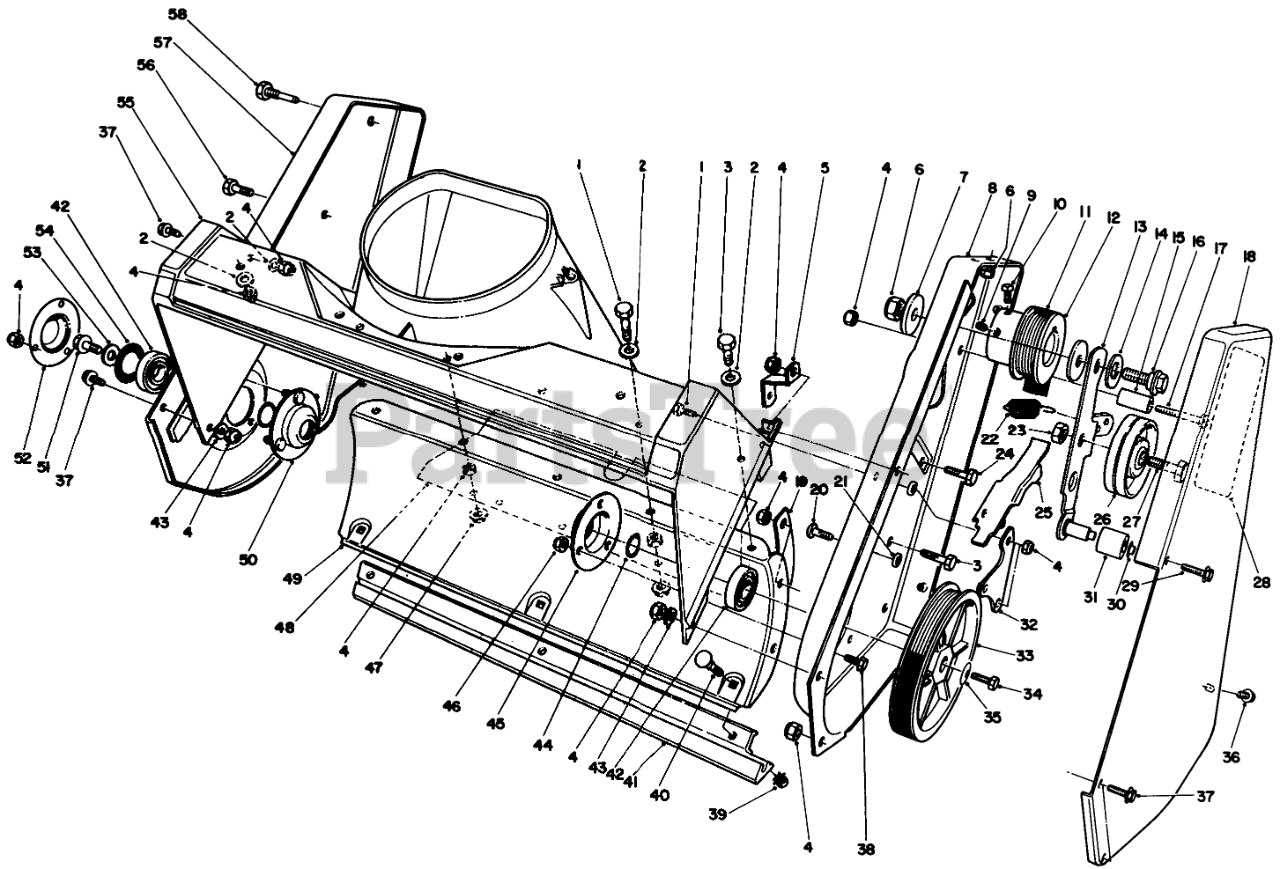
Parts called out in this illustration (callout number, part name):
1	SCREW-HH
2	WASHER-FLAT
3	SCREW-HH
4	NUT-LOCK, NI
5	BRACKET-HOUSING
6	NUT-LOCK, NI
7	WASHER-PIVOT
8	Sideplate-L.H.
9	SCREW-HSH
10	SCREW-SQH
11	BELT - DRIVE
12	ENGINE PULLEY
13	Idler Arm Assembly (Incl. Ref. #29 & 30)
14	WASHER
15	SLEEVE-GUIDE, BELT
16	SCREW-SHOULDER
17	SCREW-HH
18	Cover-Drive
19	BRACKET-HOUSING, LOWER
20	SCREW-HSBH
21	SPACER-PLATE, PIVOT
22	SPRING-EXTENSION
23	NUT-LOCK, CONE
24	SCREW-HH
25	BRAKE-ARM
26	PULLEY-IDLER
27	SCREW-HH
28	DECAL
29	SCREW-HWH, TAP
30	NUT-PUSH
31	ROLLER-BRAKE
32	PIVOT PLATE ASM
33	ROTOR PULLEY ASY
34	SCREW-HH
35	WASHER-BELLEVILLE
36	SCREW
37	SCREW-HWH
38	SCREW-SHH
39	NUT-KEPS
40	SCREW-CARR
41	SCRAPER
42	BEARING-BALL
43	WASHER-FLAT
44	WASHER-THRUST
45	FLANGE-BEARING
46	NUT-LOCK, NI
47	NUT-LOCK, HHF
48	COVER-BOTTOM
49	Housing-Lower
50	FLANGE-BEARING
51	SCREW-HHF
52	Trough
53	WASHER-FLAT
54	WASHER-RUBBER
55	HOUSING
56	SCREW-HH
57	Sideplate-RH
58	PIN-ROTOR
